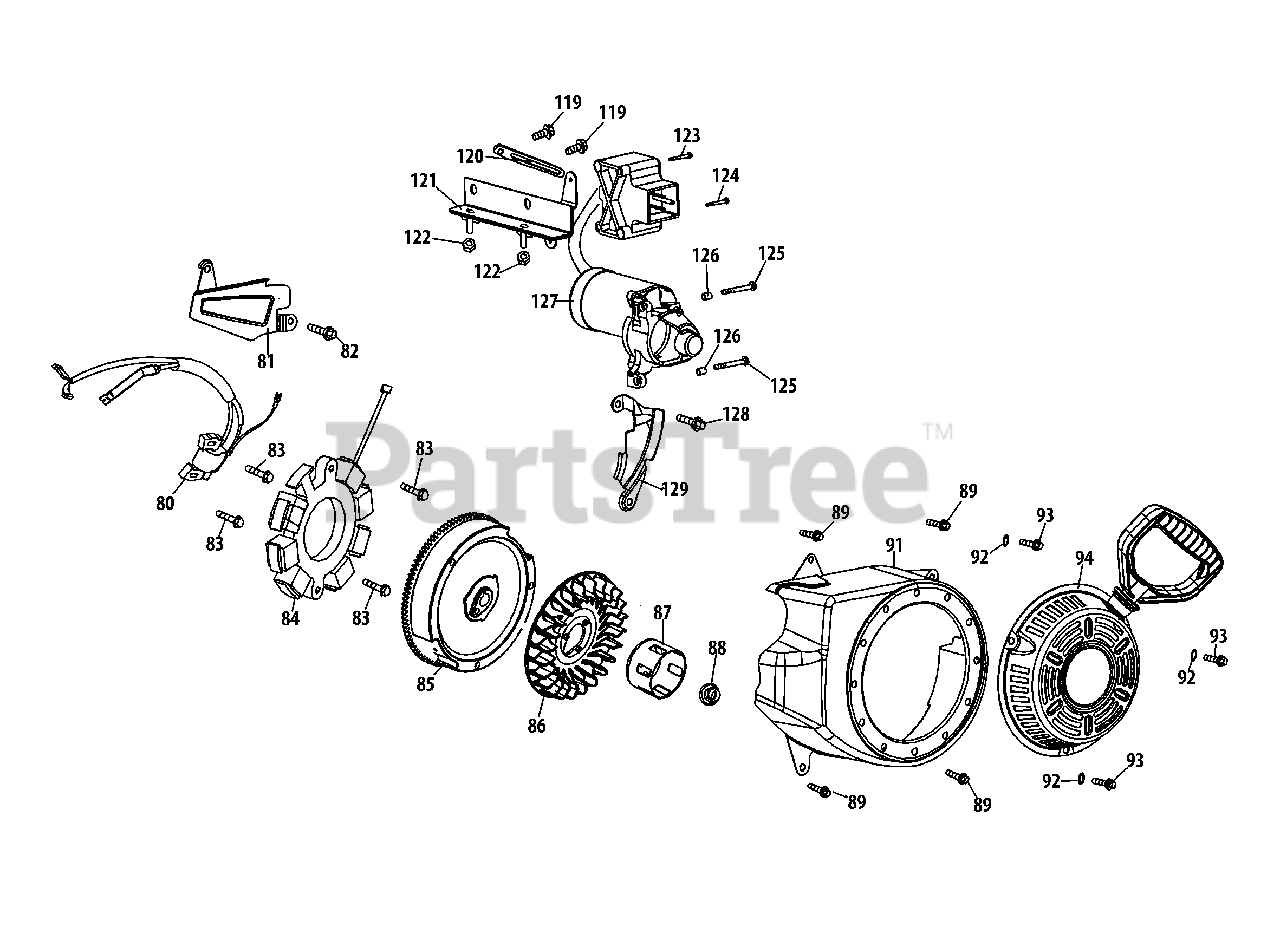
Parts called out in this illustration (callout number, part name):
80	Ignition Coil Assembly
81	Air Flow Shield
82	Bolt M6×10
83	Bolt M6×25
84	Alternator Assembly
86	Cooling Fan
87	Starter Cup
88	Flywheel Nut, M14×1.5
89	Bolt M6×12
91	Blower Housing
92	Washer 6
93	Bolt M6×10
94	Recoil Starter Assembly
119	Bolt M6×10
120	Electric Starter Cord Retainer
121	Switch Housing Mounting Bracket
123	Bolt M4×55
124	Bolt M4×60
125	Bolt M6×32
126	Dowel Pin 8×8
127	Electric Starter
128	Bolt M6×12
129	Blower Housing Shield
